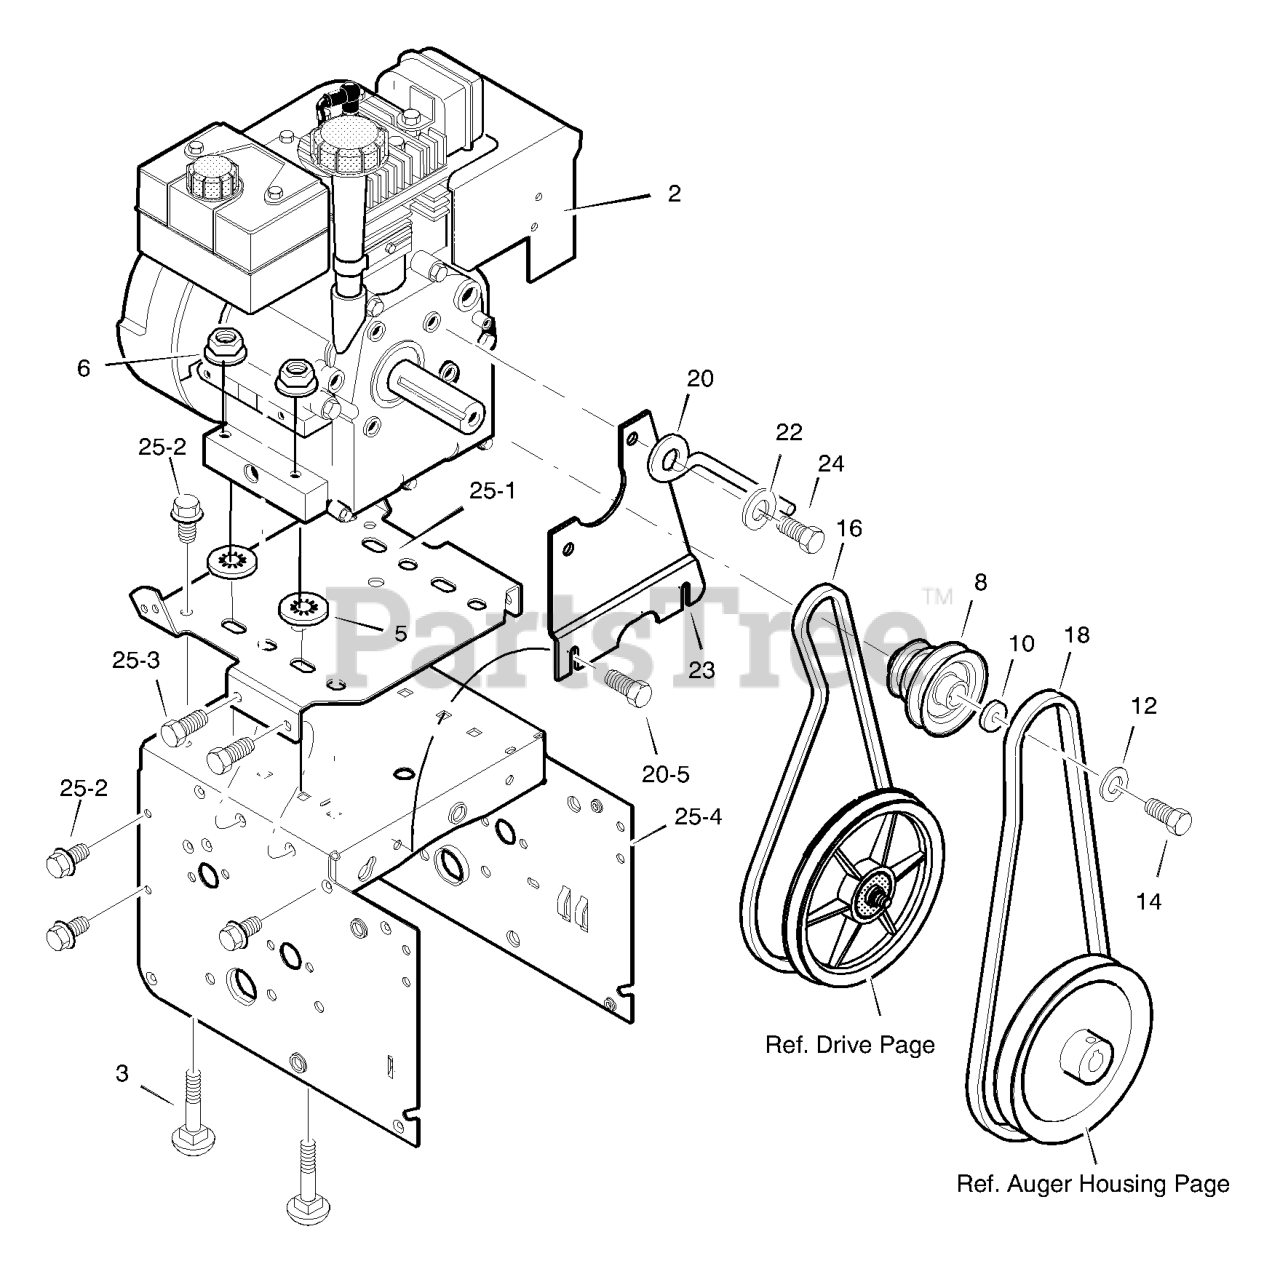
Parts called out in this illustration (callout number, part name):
2	ENGINE
3	BOLT, CARRIAGE 5/16-18
5	RETAINER, PUSH
6	NUT, HEX 5/16-18
8	PULLEY, ENGINE
10	WASHER
12	WASHER .38ID
14	SCREW, 3/8-24 x 1.00
16	BELT, V 3L
18	BELT, V 4L
20	GUIDE, BELT
22	WASHER, SPTLK .31X.58X.08
23	PLATE, ANTI VIBRATION
24	SCREW, 5/16-24 x 1.00
25	FRAME ASSEMBLY
25-1	PLATE, ENGINE MOUNT
25-2	SCREW, TAP 1/4-20 X 0.62
25-3	SCREW, TAP 5/16-18 X 0.50
25-4	FRAME, MOTOR BOX
